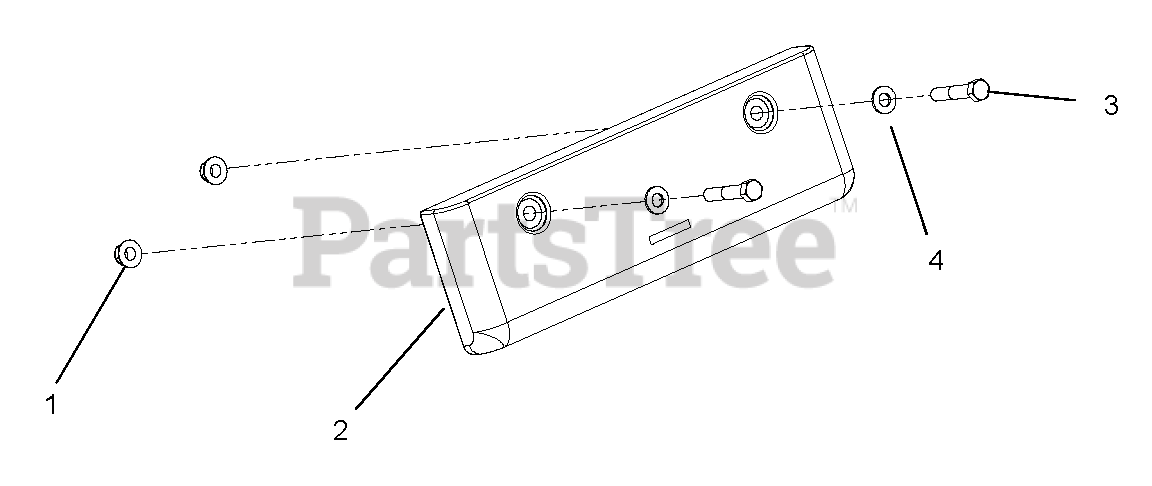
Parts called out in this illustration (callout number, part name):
1	@NUT-LK-NYL-FLG .50-13 YWZC
2	WEIGHT, CAST IRON
3	@BLT-HEX .50-13X2.75 GR5 YWZC
4	@WSHR-FL-STL.531X1.06X.095YWZC
